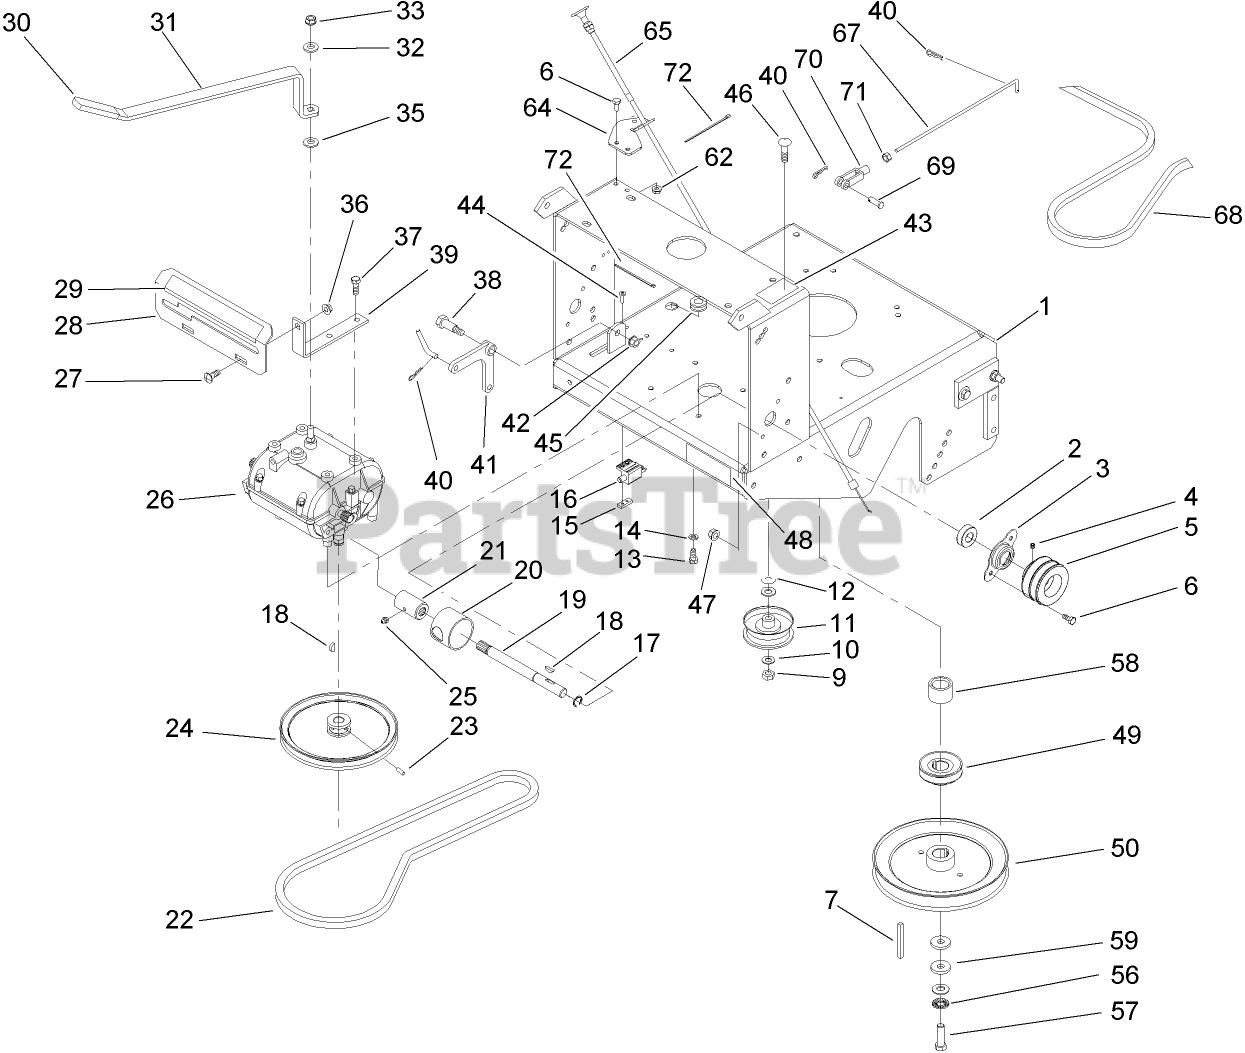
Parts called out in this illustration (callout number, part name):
1	DECK-ENGINE
2	BEARING-SHAFT
3	FLANGE-OUTPUT
4	SCREW-SET
5	SHEAVE-TRANSMISSION
6	SCREW-HH
9	NUT-LOCK, NI
10	WASHER-FLAT
11	PULLEY-IDLER, FLAT
12	WASHER-FLAT
13	SCREW-HH
14	WASHER-LOCK
15	PLATE-TAPPED
16	SWITCH-CLOSED, NORMALLY
17	RING-RETAINING
18	KEY-WOODRUFF
19	SHAFT-TRANSMISSION
20	GUARD-COUPLER
21	COUPLER
22	V-BELT
23	SCREW-HSH
24	SHEAVE-TRANSMISSION
25	FITTING-GREASE
26	TRANSMISSION
27	BOLT-CARR
28	PLATE-SHIFT
29	DECAL-SPEED, GROUND
30	GRIP-LEVER
31	LEVER-SHIFT
32	WASHER-BELLEVILLE
33	NUT-LOCK
35	WASHER
36	NUT-HF
37	SCREW-HWH, THREAD CUT
38	BOLT-SHOULDER
39	BRACKET-PLATE, SHIFT
40	PIN-COTTER
41	BELLCRANK
42	NUT-HHF, WHIZ
43	DECAL-SHUT OFF, FUEL
44	SCREW-PPH
45	GROMMET
46	SCREW-CARR
47	NUT-LOCK, NI
48	DECAL-CAUTION
49	Sheave-Transmission
50	PULLEY ASM
56	WASHER-SPRING
57	SCREW-HH
58	SPACER-CLUTCH
59	WASHER
62	NUT-HF
64	Bracket-Cable, Choke
65	Cable-Choke
67	ARM-ASSIST, LINKAGE
68	BELT-V
69	PIN-CLEVIS
70	YOKE-ADJUSTABLE
71	NUT-HEX
72	TIE-PLASTIC
